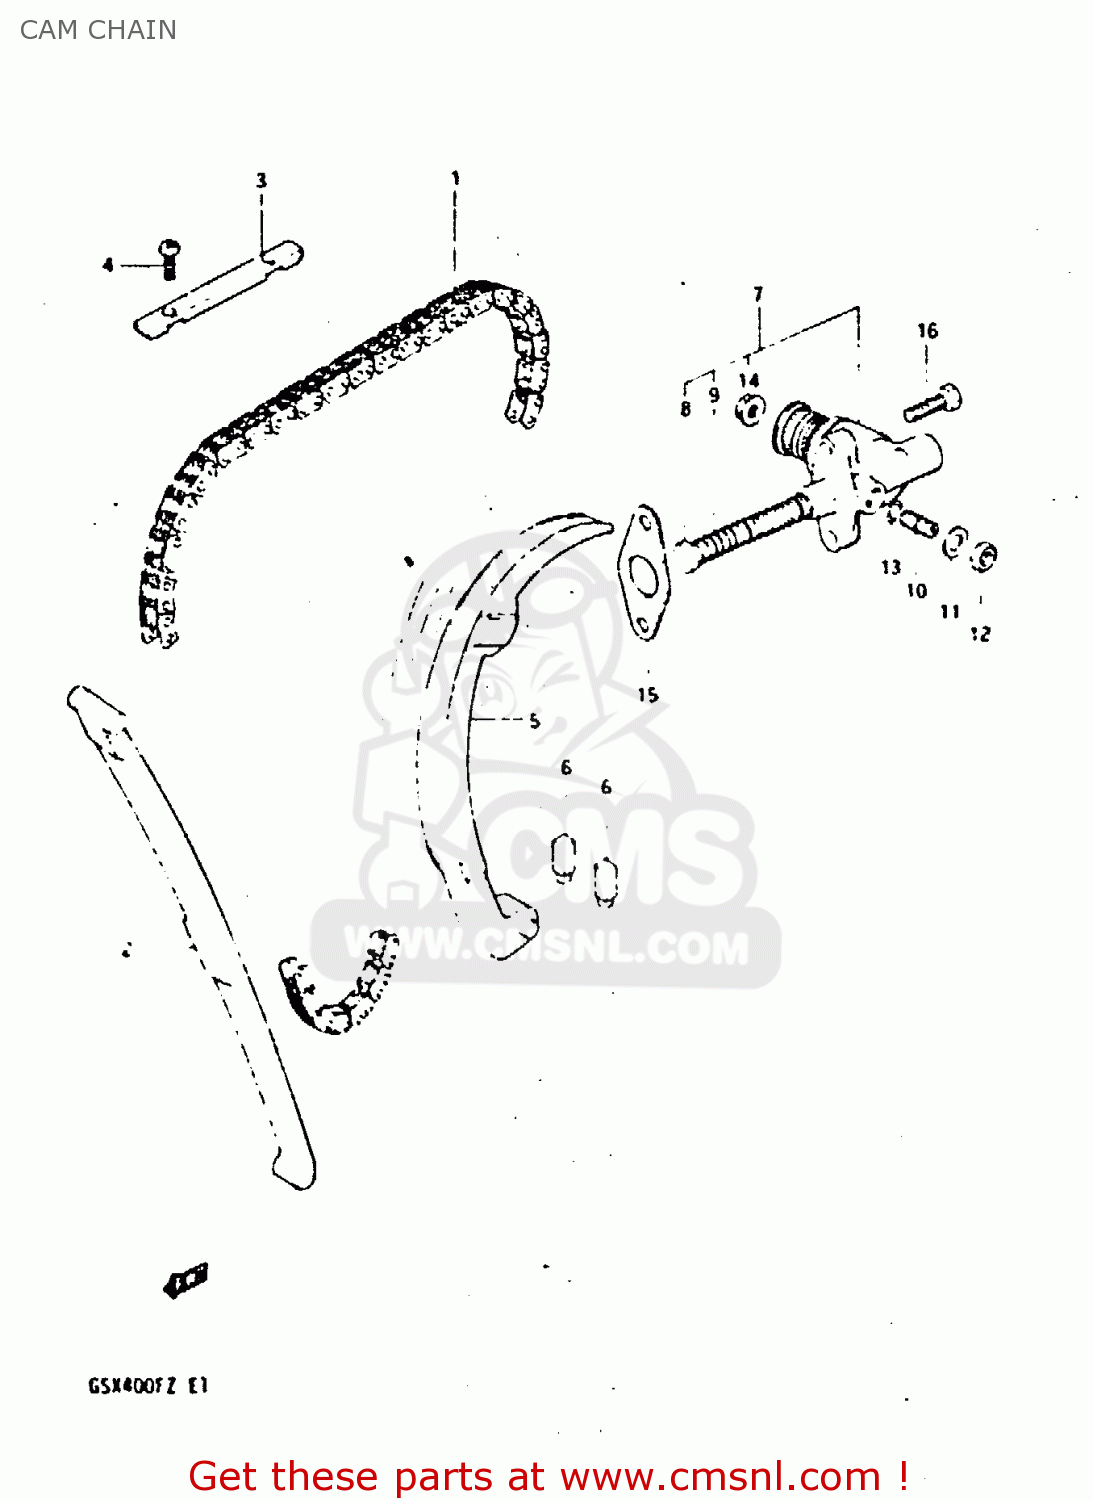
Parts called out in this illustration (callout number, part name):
1	CHAIN, CAM SHAFT DRIVE
2	GUIDE,CAM CHAIN NO.1
3	GUIDE,CAM CHAIN NO.2
4	SCREW
5	TENSIONER,CAM CHAIN
6	CUSHION,CAM CHAIN TENSIONER
7	ADJUSTER ASSY, TENSIONER
8	ROD,PUSH
9	SPRING
10	SCREW
11	WASHER
12	NUT
13	O-RING
14	NUT
15	GASKET,TENSIONER ADJUSTER (MCA)
16	SCREW (6X25)
